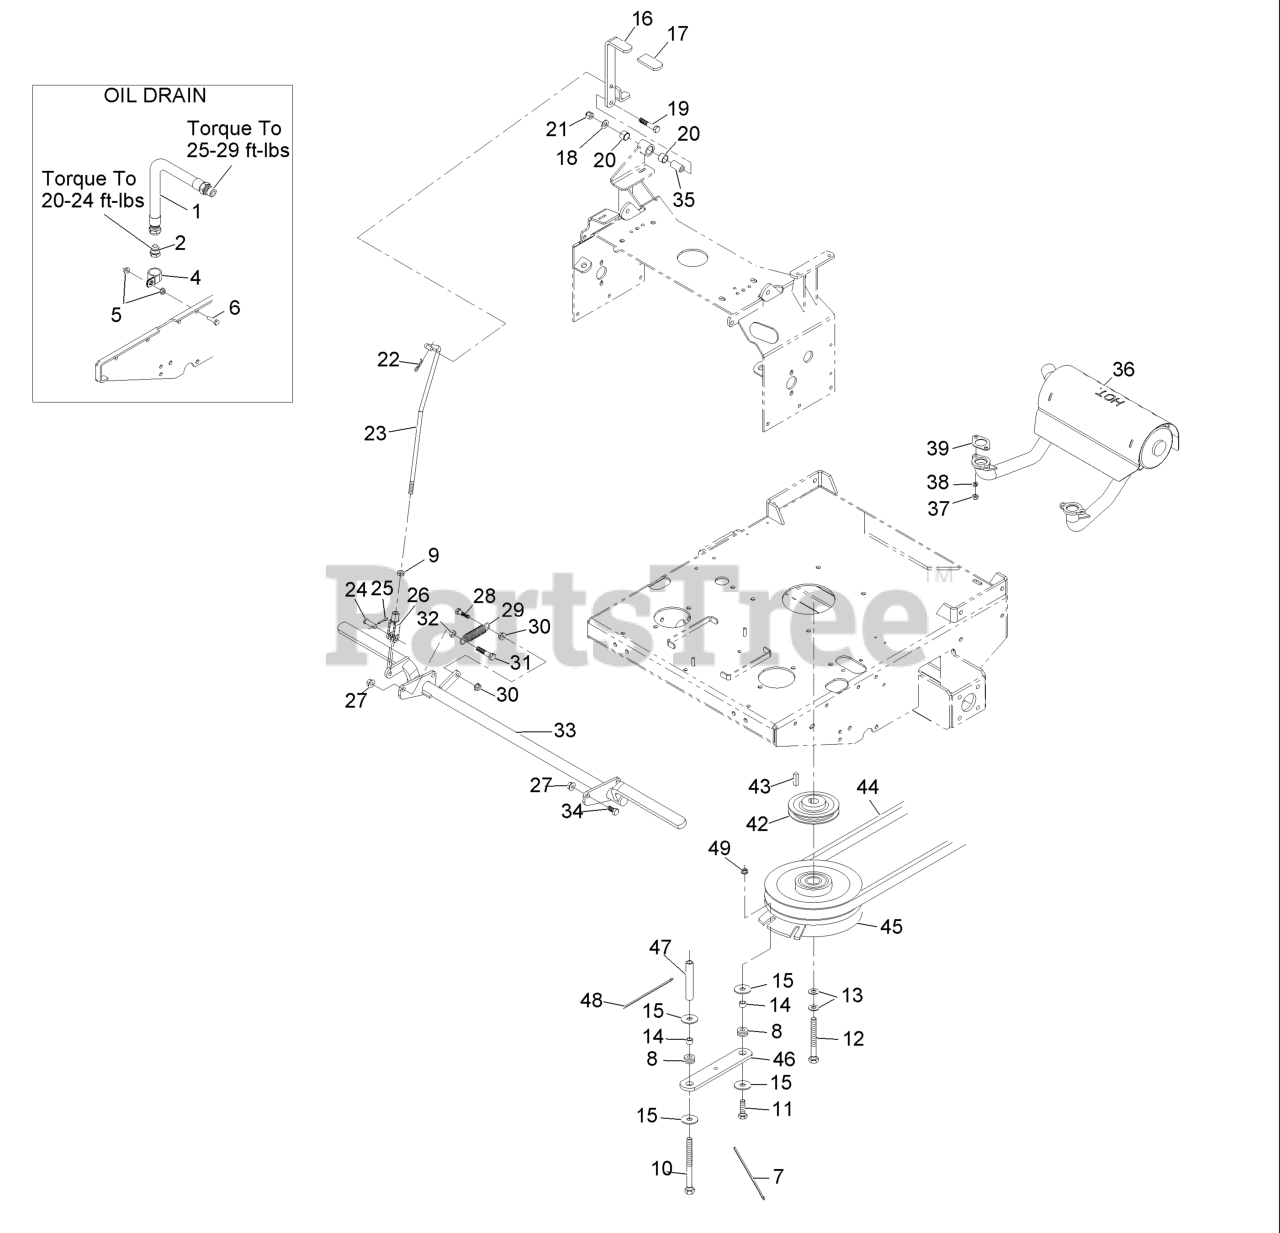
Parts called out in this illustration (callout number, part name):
4	CLIP-LOOM
6	SCREW-HH
7	TIE-PLASTIC
8	GROMMET
9	NUT-HJ
10	SCREW-HH
11	SCREW-HH
12	SCREW-HH
13	WASHER-SPRING
16	LEVER,PRK BRK W/DECALS
17	GRIP-LEVER
18	WASHER-FLAT
19	SCREW-HH
20	SLEEVE-BUSHING
21	NUT-LOCK, NI
22	PIN-COTTER
23	LINKAGE, PARK BRAKE
24	PIN-CLEVIS
25	PIN-COTTER
26	YOKE-LINKAGE, BRAKE
27	NUT-HHF, WHIZ
28	SCREW-HH, SPECIAL
29	SPRING-IDLER
31	SCREW-HH
32	NUT-JAM
34	SCREW-HH
35	BUSHING-PIVOT
36	MUFFLER,HORIZONTAL
38	WASHER-LOCK
39	GASKET-EXHAUST
42	PULLEY
44	BELT,B 83.65
44	BELT,DECK DRIVE
45	CLUTCH ASM
46	STRAP-CLUTCH, BRAKE
47	SPACER,SHIELD
48	TIE-CABLE
